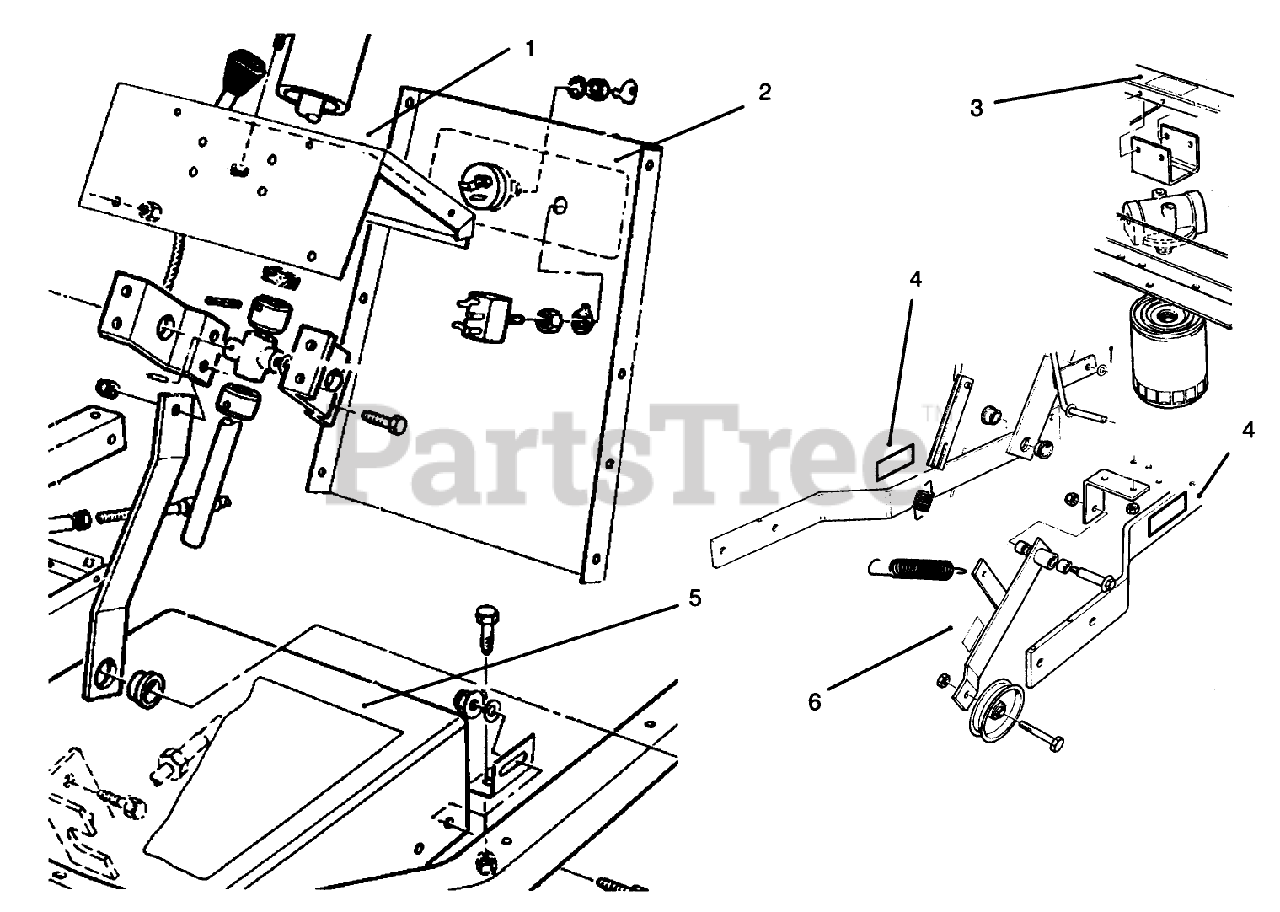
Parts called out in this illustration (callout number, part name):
1	DECAL - THROTTLE, CHOKE
2	DECAL - SWITCH
3	DECAL-OIL
4	DECAL-WARNING
5	DECAL - TUNNEL
6	DECAL-WARNING
